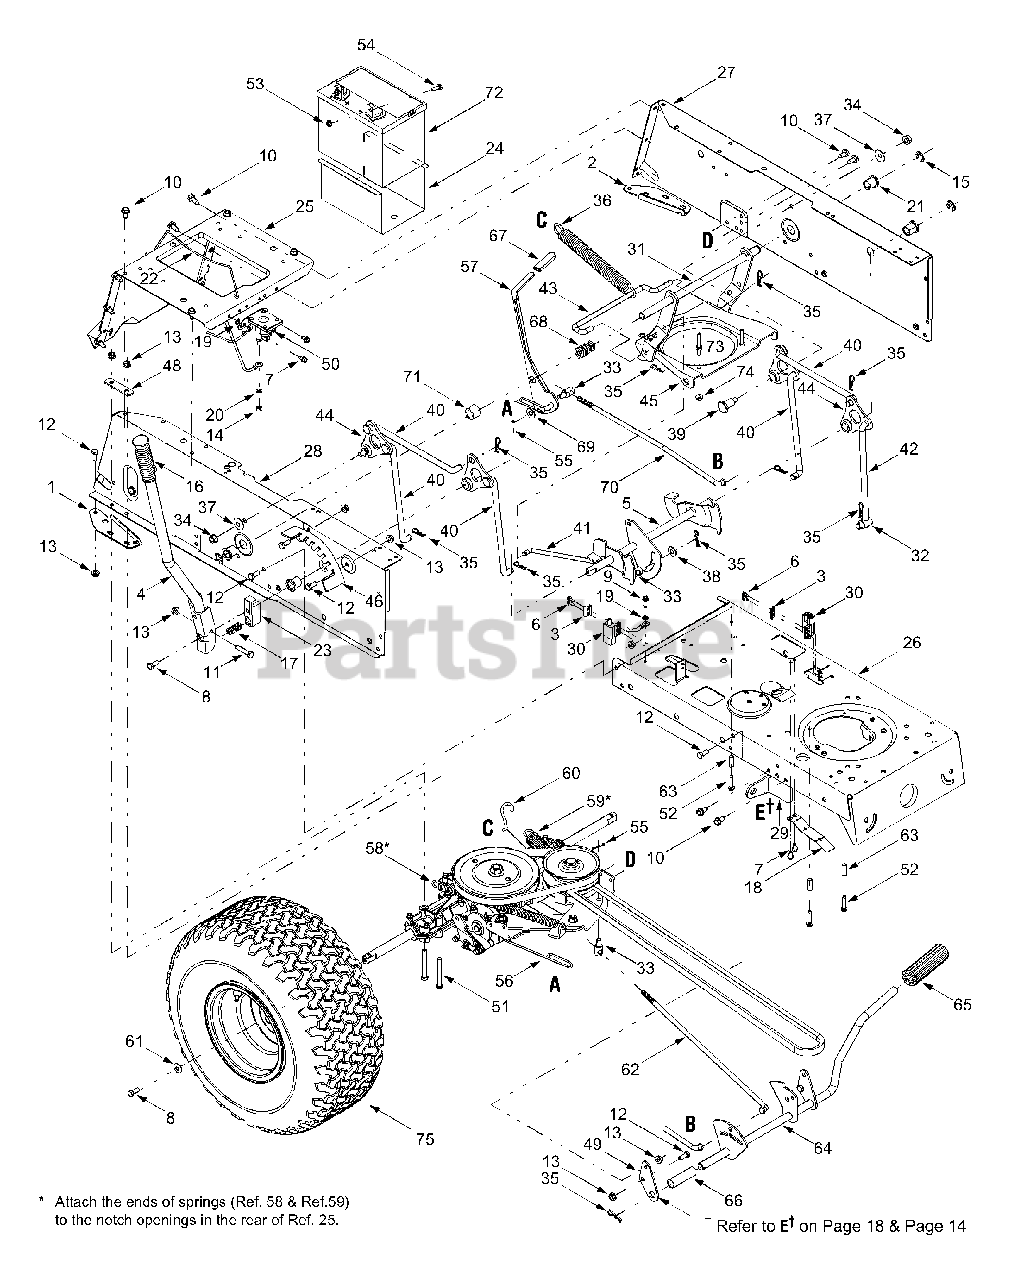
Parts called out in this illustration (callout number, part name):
6	Self-tapping Screw, #10-16 x .5
7	Self-tapping Screw, 1/4-20 x .5
8	Hex Cap Screw, 5/16-24 x .75
9	Self-tapping Screw, 1/4-20 x .75
10	Self-tapping Screw, 5/16-12 x .75
11	Hex Cap Screw, 5/16-18 x 1.5
12	Hex Screw, 5/16-18 x .75
13	Flange Lock Nut, 5/16-18
14	Hex Nut, 1/4-20
15	E-Ring, .625 Dia Shaft
16	Handle Grip
17	Compression Spring, .55 x 1.37
18	Switch Actuator Spring
19	External Lock Washer, 1/4
20	Lock Washer, 1/4
21	Flange Bearing, .632 ID
22	Battery Hold-down Rod
23	Lift Shaft Connector
33	Ferrule, 3/8-24 x .375
34	Flange Lock Nut, 3/8-16
35	Internal Cotter Pin, .080 x 1.56
36	Extension Spring, 1.07 x 9.52
37	Bell Washer, .389 x 1.12 x .030
38	Flat Washer, .385 x .87 x .060
39	Shoulder Bolt, 3/8-16 x .62 x .92
40	Deck Hanger Link
41	Deck Disengagement Rod
42	Deck Hanger Link
43	Rear Stabilizer Rod
44	Lift Link
51	Hex Cap Screw, 5/16-18 x 2.75
52	Self-tapping Screw, 1/4-20 x 1.25
53	Hex Sems Nut, 1/4-20
54	Hex Screw,1/4-20 x .75
55	Cotter Pin, 1.0
56	Extension Spring, .59 x 12.38
57	Speed Select Lever
58	Extension Spring, .73 x 12.54
59	Extension Spring, 1.15 x 7.90
60	Brake Return Spring
61	Bell Washer, .34 x .872 x .060
62	Variable Speed Control Rod
63	Spacer, .260 x .372 x 1.030
66	Spacer, .640 x .76 x 2.63
67	Shift Handle Grip
68	Compression Spring, .89 x 1.75
69	Flat Washer, .406 x .875 x .059
70	Speed Control Rod
71	Spacer, .640 x 1.0 x .78
72	Battery, 270 CCA
73	Flange Lock Nut, 1/4-20
74	Belt Guard Pin, 1/4-20
